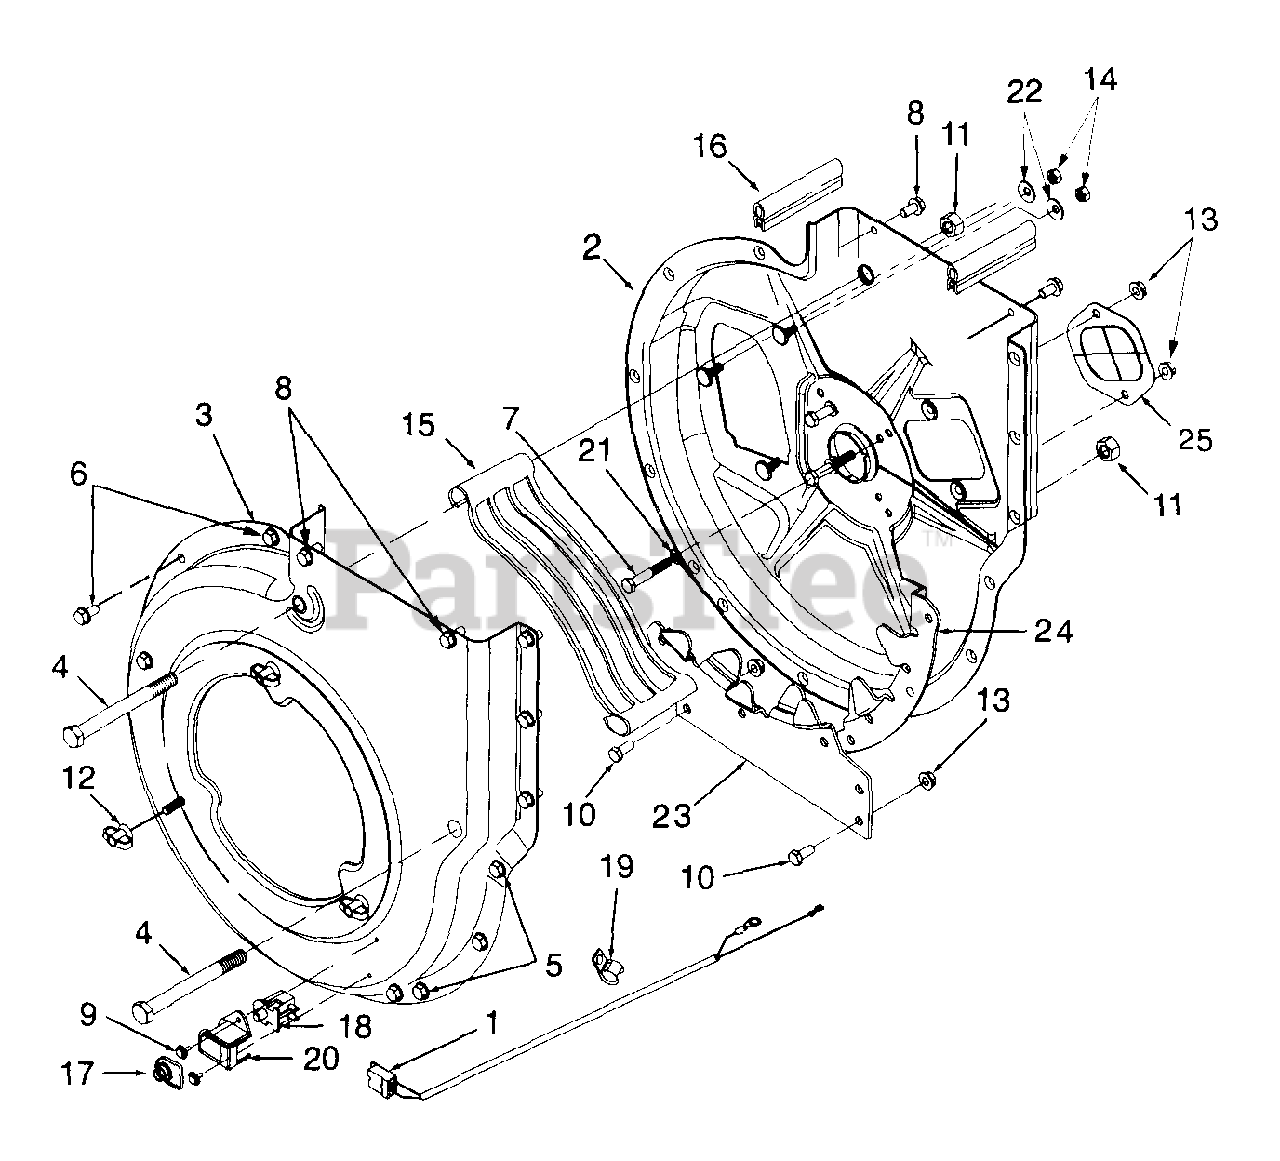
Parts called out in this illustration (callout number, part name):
1	Harness, Wire
2	Housing Ass'y, Inner Flail
3	Housing Ass'y, Outer Flail
4	Screw, Hex Cap, 1/2-13 x 5.0
5	Screw, Hex Wash Hd Tapp 5/16-18 x .62
6	Screw, Hex Wash Hd Tapp 5/16-18 x .50
7	Screw, Hex Cap, 5/16-24 x 2 GR5
8	Screw, Hex Wash Hd Tapp 5/16-18 x .75
9	Screw, Hex Wash Hd Tapp #10-16 x .38
10	Screw, Hex Cap, 5/16-18 x .75 GR5
11	Nut, Hex Center Lock, 1/2-13
12	Knob, 5/16-18
13	Nut, Hex Flange Lock, 5/16-18
14	Nut, Hex, 5/16-18
15	Screen, Discharge
16	Rubber Seal
17	Cover, Switch
18	Switch, Snap Mount
20	Cover, Safety Switch Mtg.
21	Washer, Lock, 5/16
22	Washer, Bell, .345 x .88 x .06
